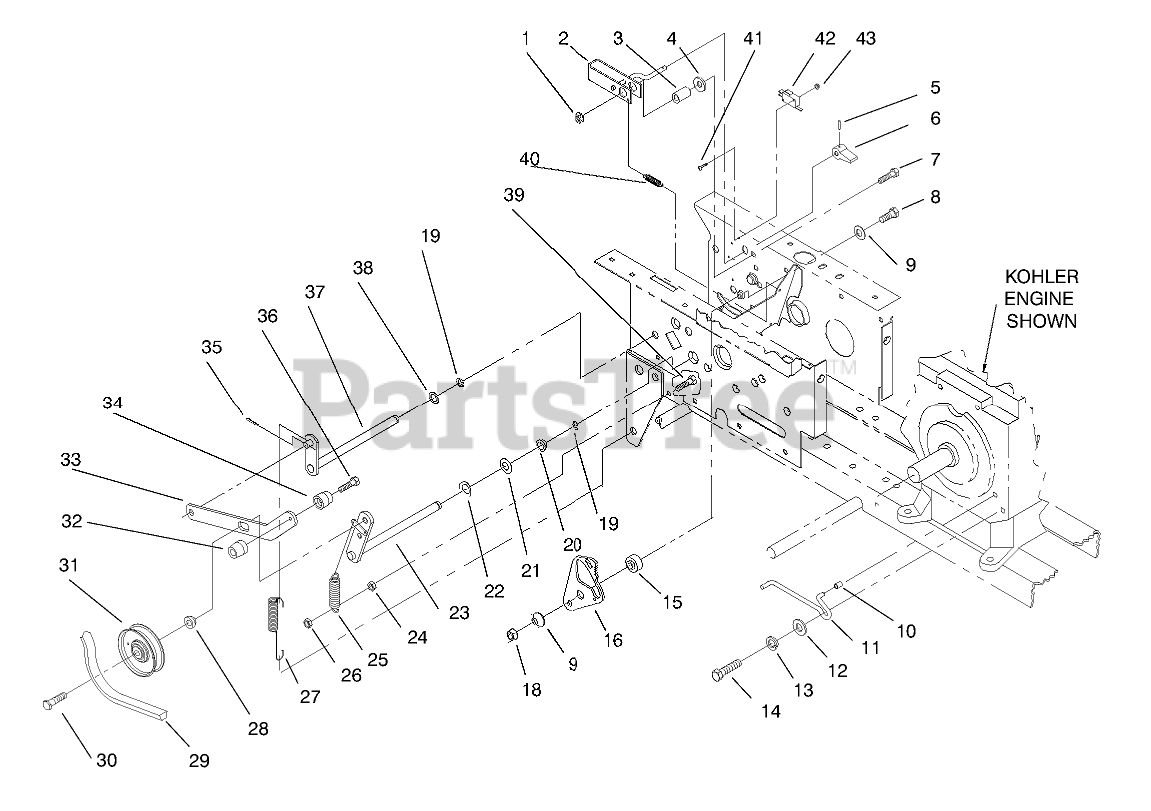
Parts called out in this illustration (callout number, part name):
1	NUT-HF
2	WLMT-BRAK (BLACK)
3	SPACER
4	WASHER-SPACER
5	PIN-SPIROL 3/32X5/8
6	KNOB-PARKING BRAKE
7	SCREW-HH
8	SCREW-HH
9	WASHER-FLAT
11	GUIDE BELT
12	WASHER-FLAT
13	WASHER-LOCK
14	SCREW-HH
15	Spacer
16	PLATE-CAM (BLACK)
18	NUT-LOCK, NI
19	RING-RETAINING, EXTERNAL
20	BUSHING-FLANGED
21	SHIM-WASHER
22	CURVED-SPRING WASHER
23	ASSY-ARM/ROD WA
24	NUT-HEX
25	SPRING-EXTENSION
26	NUT-LOCK, NI
27	SPRING-EXTENSION
28	SPACER-BRAKE LINK
29	V-BELT TRANS DRIVE
30	BOLT-SPECIAL HEX
31	PULLEY-IDLER
32	KNOB
33	HNDL BRAKE & CLUTCH (BLACK)
34	KNOB
35	PIN-COTTER
36	Screw
37	ASSY-BRAKE LEVER
38	WASHER
39	SCREW-HH
40	EXTENSION-SPRING
41	SCREW-PPH
42	SWITCH
43	NUT-HEX
